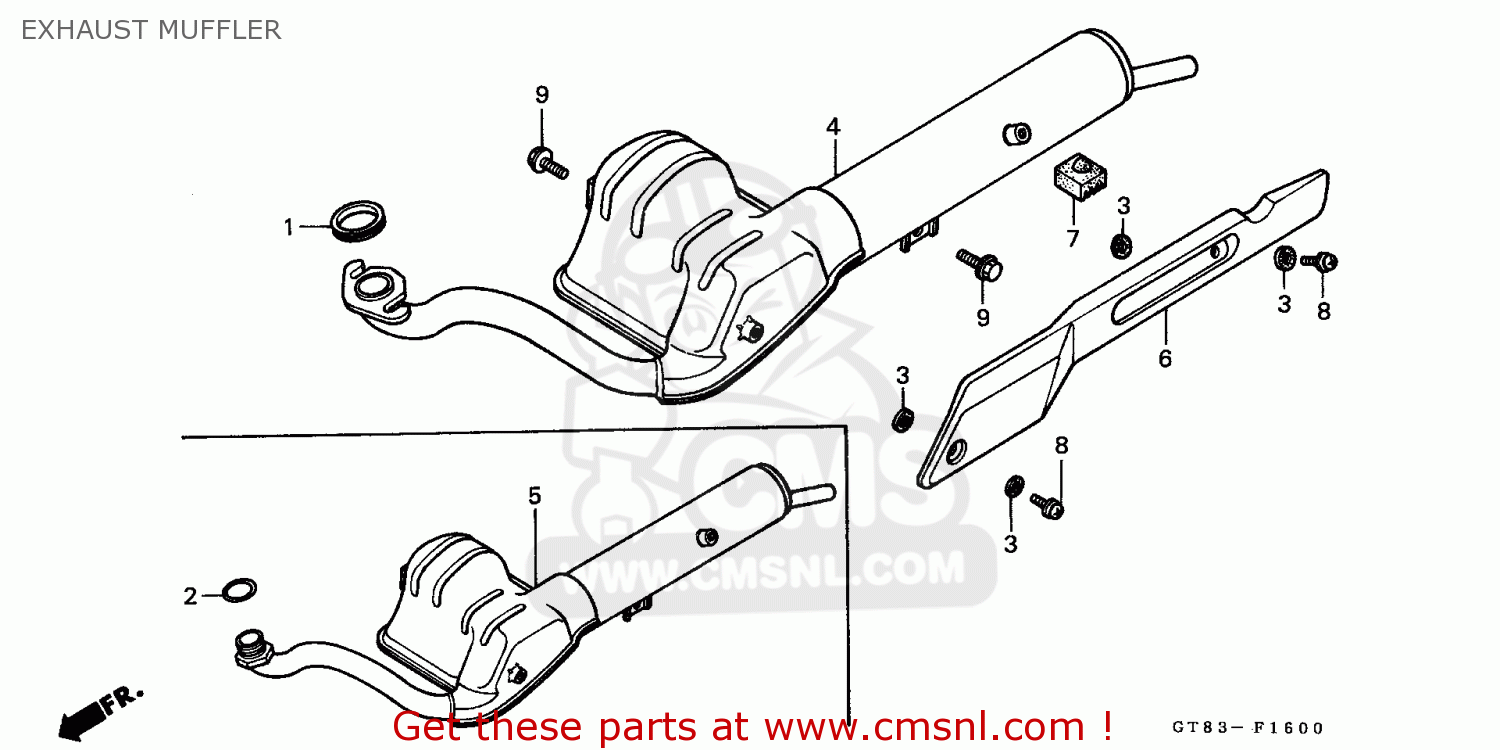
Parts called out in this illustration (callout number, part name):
1	GASKET,EX.PIPE (NAS)
3	PKG.,MUFF.PROTR. (NAS)
4	MUFFLER COMP.,EX.
6	PROTECTOR,MUFF.
7	RUBBER,STAND STOP
8	SCREW-WASH.,5X8
9	BOLT,FLANGE,8X12
